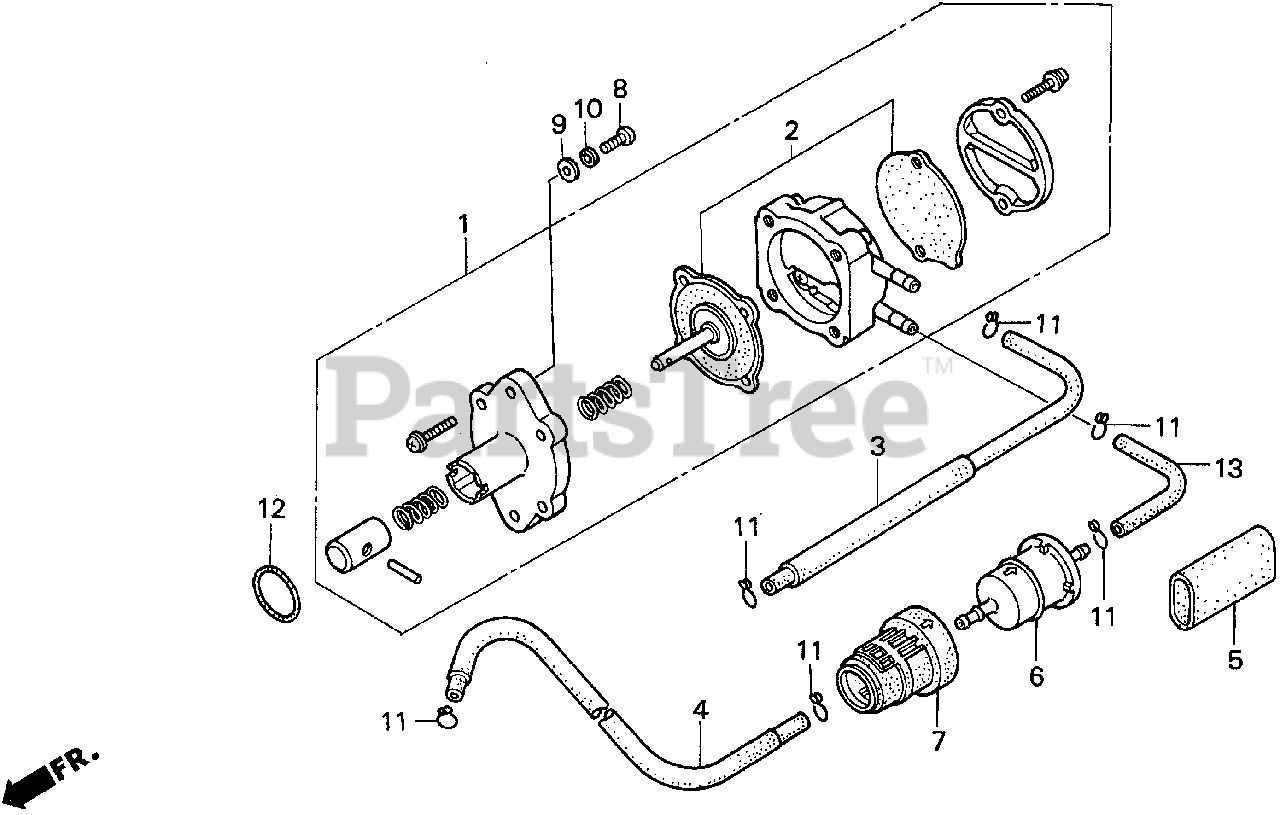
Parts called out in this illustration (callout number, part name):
1	PUMP ASSY., FUEL
3	TUBE A, FUEL
4	TUBE B, FUEL
5	PROTECTOR, TUBE
6	FILTER, FUEL
7	SUSPENSION, STRAINER
8	SCREW, PAN (6X22)
9	WASHER, PLAIN (6.2MM)
10	WASHER, SPRING (6MM)
11	CLIP, TUBE (B10)
12	O-RING (20.8X2.4)
13	BULK HOSE, FUEL (5.5X8000) (5.3X90)
